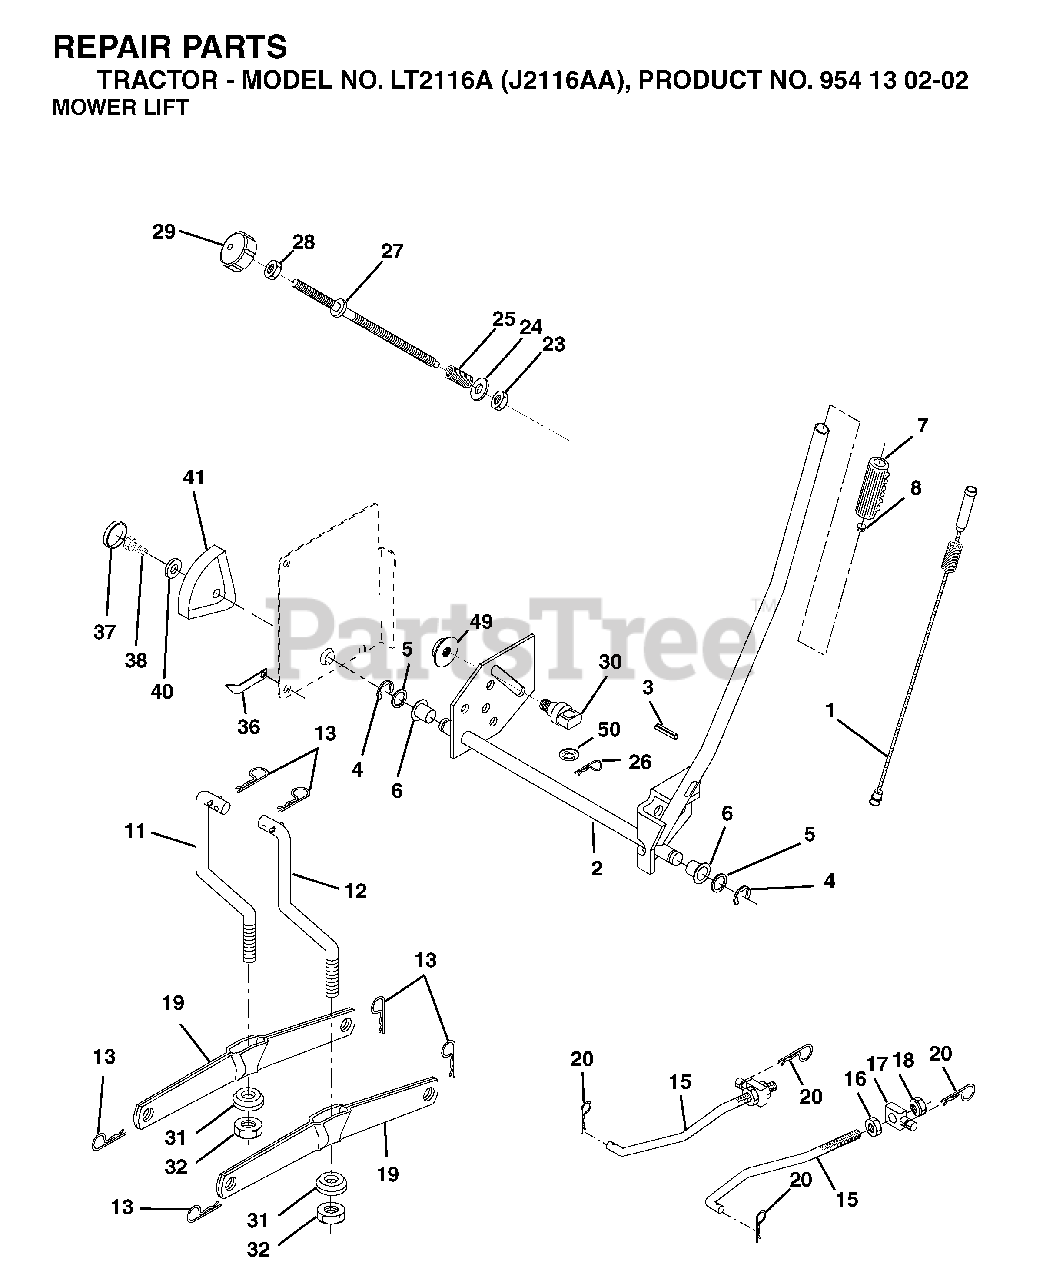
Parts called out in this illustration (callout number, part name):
1	WIRE ASM INNER W/ PLUNGER LT
2	SHAFT ASM R HANDLE
3	PIN GROOVE
4	RETAINING RING LT
6	BEARING.NYLON
7	GRIP HANDLE
11	LINK LIFT LH
12	LINK LIFT RH
13	RETAINER-SPRNG RB
15	LINK.SUSPENSION.FRONT
16	NUT
18	NUT
19	ARM.REAR.SUSPENSION
20	SPRING RETAINER
25	SPRING**
26	RETAINER CLIP
27	ROD ADJ LIFT
28	NUT
29	KNOB INF 3/8-16
31	BEARING.PIVOT.LIFT
32	NUT CROWNLOCK 3/8-24
36	POINTER, HEIGHT INDICATOR
37	PLUG,HOLE
38	SCREW 5/16-18X1
41	IND. HEIGHT STLT
49	NUT
50	NUT PUSH M
